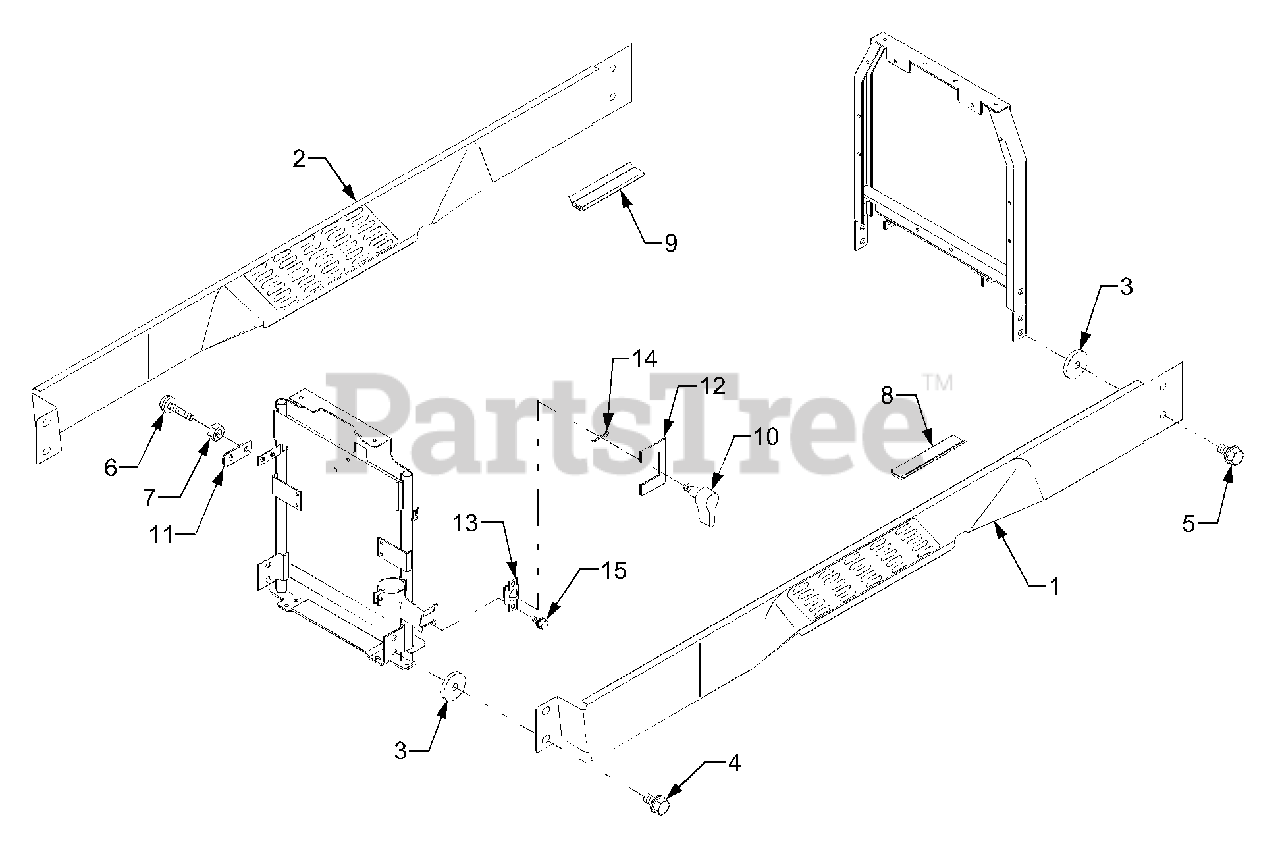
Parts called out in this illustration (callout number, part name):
1	Cover, Low (LH)
2	Cover, Low (RH)
6	Bolt, Cushion
8	Rubber, Cover (LH)
9	Rubber, Cover (RH)
10	Knob, Side Cover
11	Plate, Side Cover
12	Rubber (Bonnet-LH)
